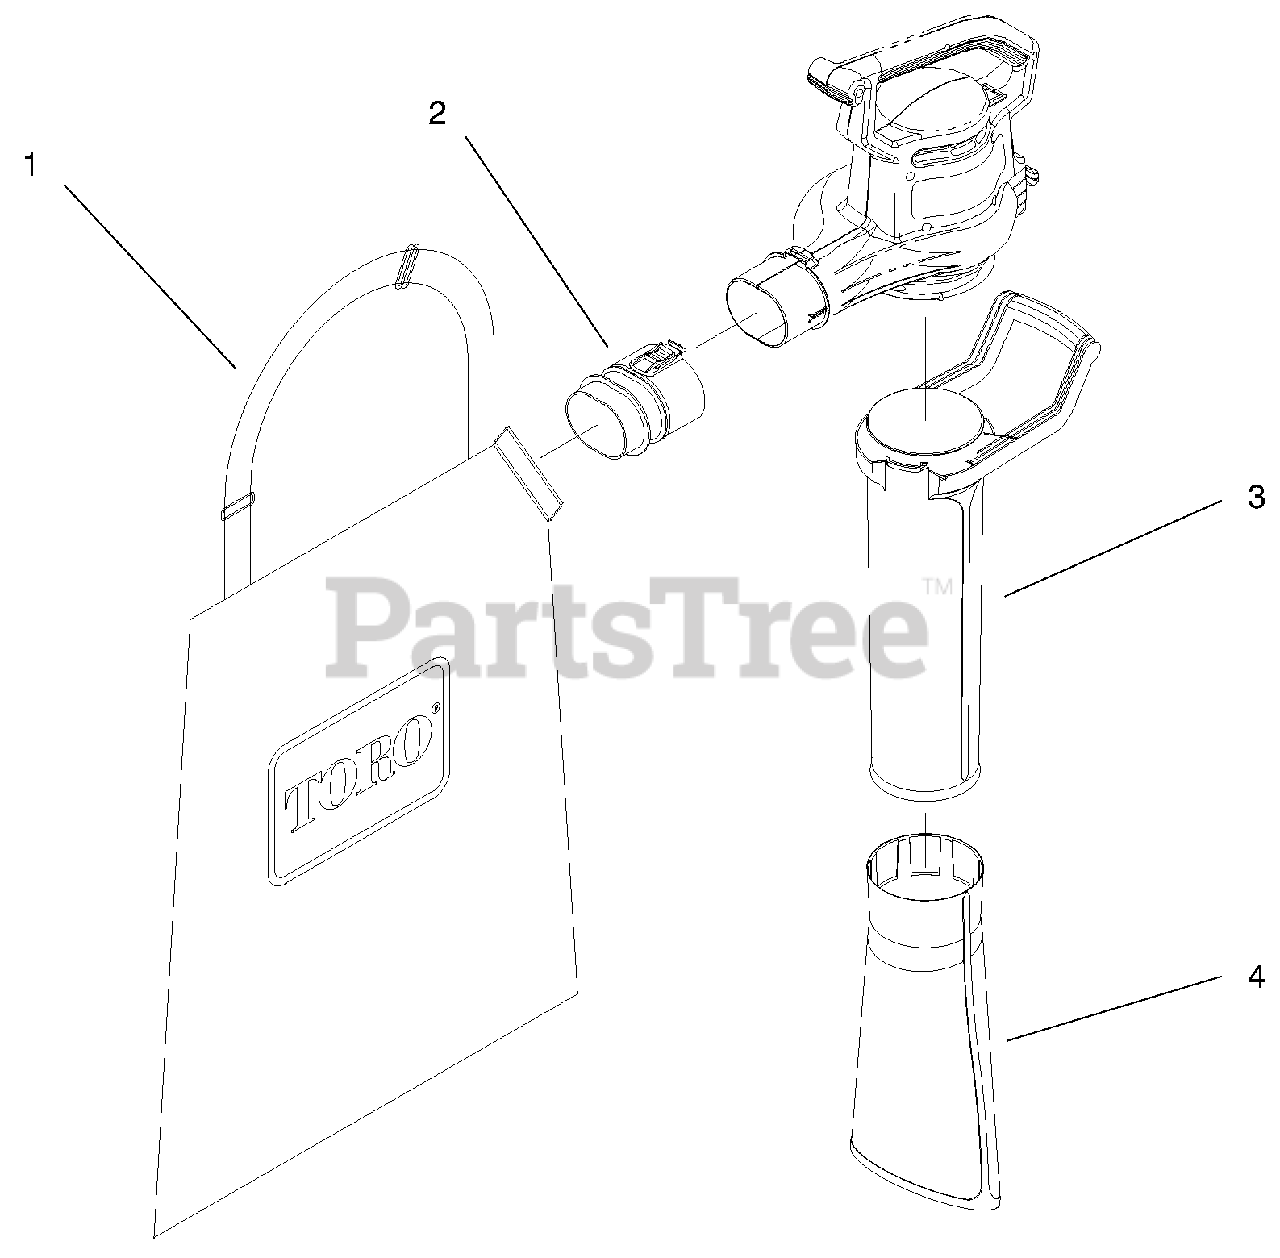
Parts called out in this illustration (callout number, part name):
1	Bag
2	Tube-Bag Inlet
3	Tube-Vac Upper
4	Tube-Vac Lower
